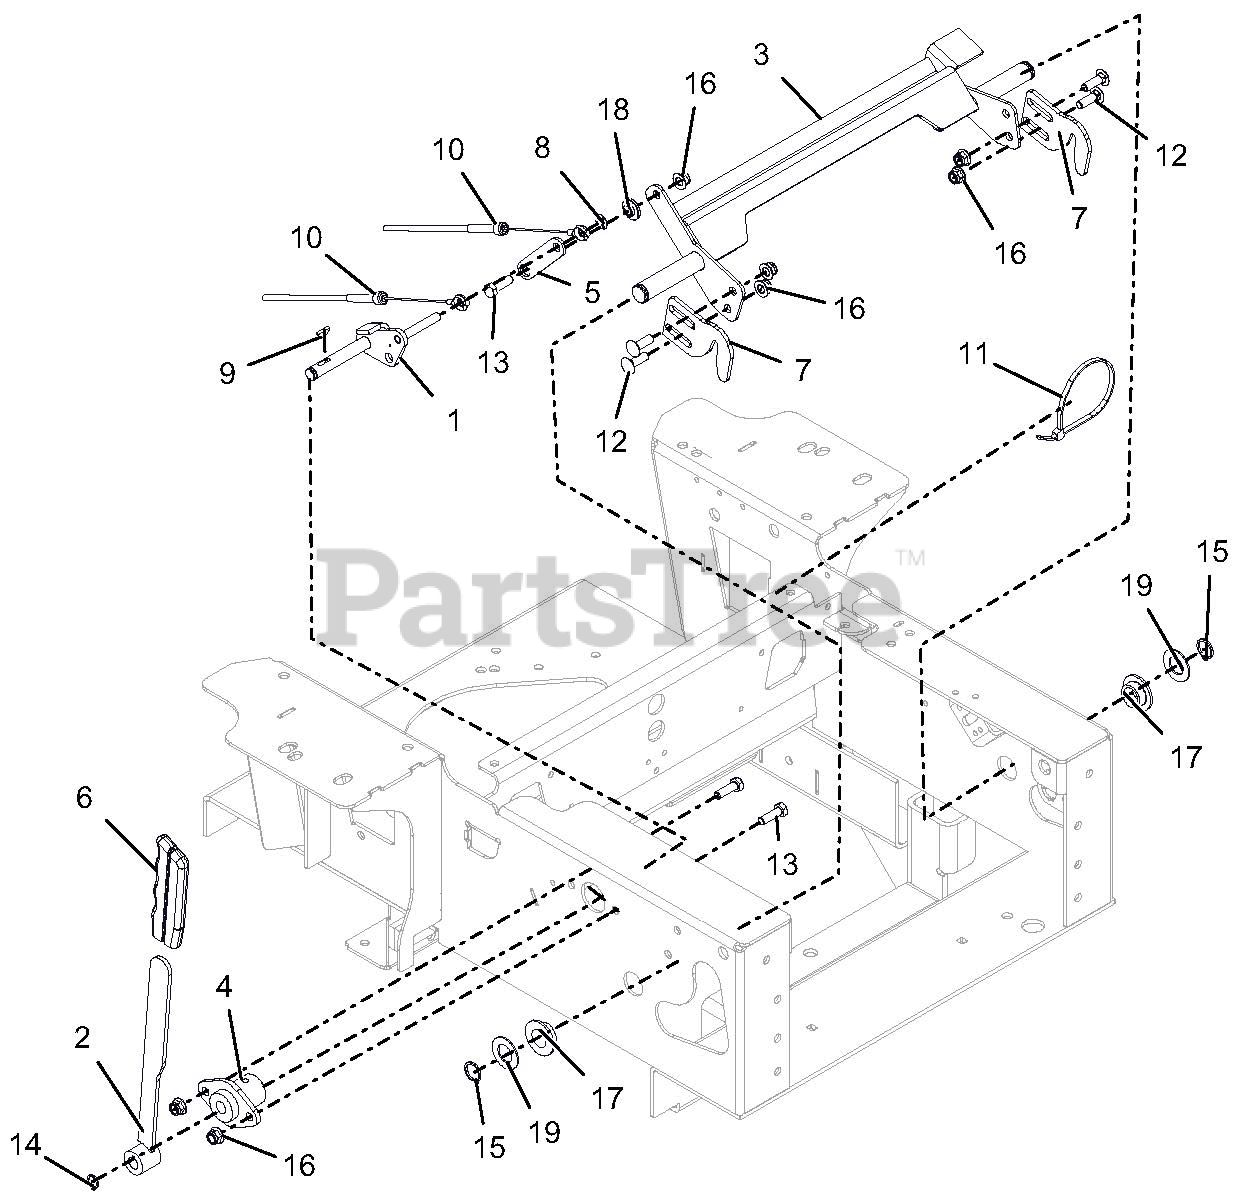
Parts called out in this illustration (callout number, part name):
1	WLDMT, PARK BRAKE ARM
2	WLDMT, PARKING BRAKE ARM
3	WLDMT, PT100 NEUTRAL LOCK
4	BSHG, FLANGE .500 ID
5	PLATE, NEUTRAL INTERLOCK
6	GRIP, PARKING BRAKE (YELLOW)
7	NEUTRAL, LOCK LATCH-BLACK
8	NUT, PUSH .312
9	KEY, WDRF .13x.63 HRD#5 GM124545 P
10	CABLE, BRAKE ACTUATING
11	CABLE, TIE 5.50 LG
12	BLT-RDHDSQSHNK .31-18X1.00 G5 Y
13	BLT-HEX .31-18X1.00 GR5 YWZC
14	RG-RTNG-EXT .500x.050
15	RG-RTNG-EXT .750x.078
16	NUT-LK-NYL-FLG .31-18 YWZC
17	BSHG, FLANGE .750 X 1.00 X .625 X 1.25
18	BSHG, FLG .325X.499X.26X.88
19	WSHR-FL-STL .755X1.375X.062 YWZC
